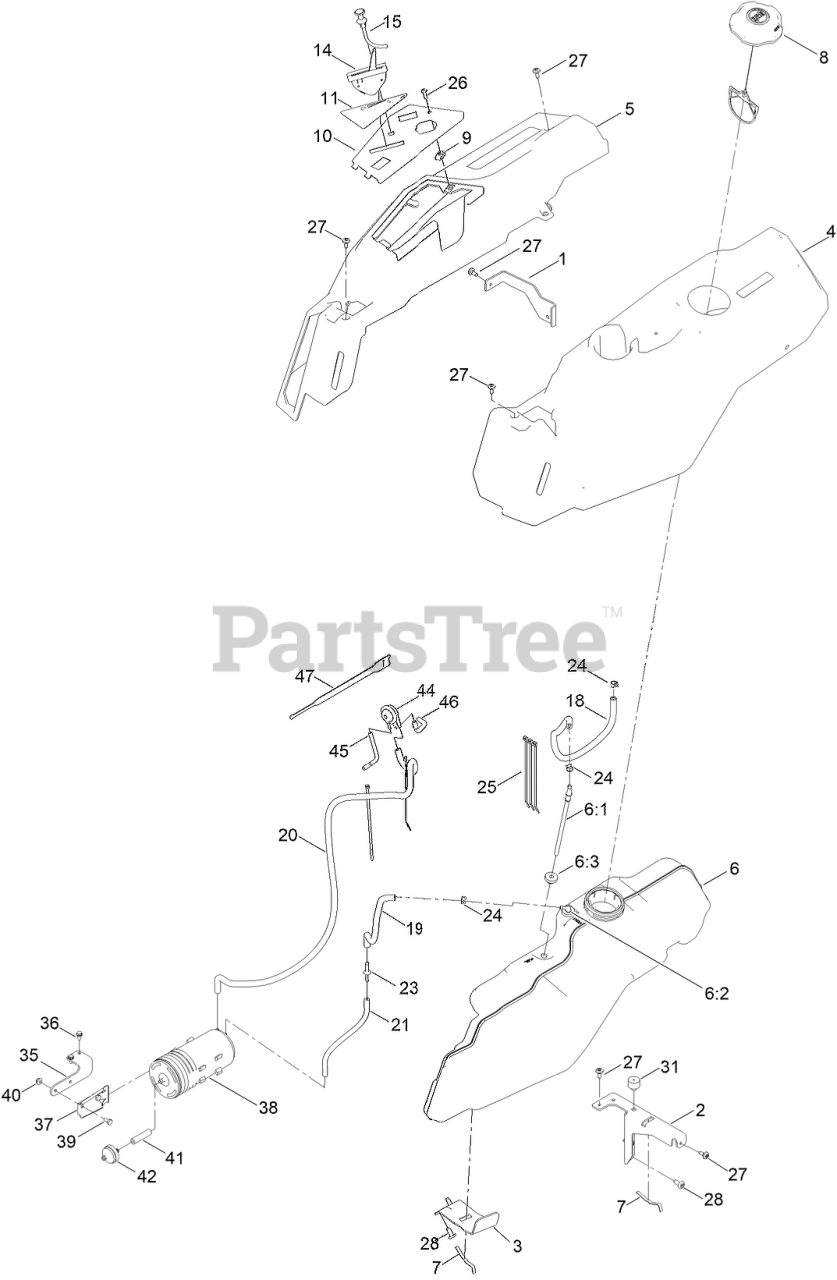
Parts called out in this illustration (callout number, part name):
1	BRACKET-POD
2	SUPPORT-POD, LH
3	SUPPORT-TANK, FUEL
4	POD-LH
5	POD-RH, MYRIDE
6	FUEL TANK ASM
6:1	CONNECTOR-ELBOW, 90 DEG
6:2	FITTING-PLASTIC
6:3	BUSHING
7	SPRING
8	CAP-FUEL, RATCHETING
10	PANEL - CONTROL
11	DECAL-PANEL, CONTROL
14	CABLE-THROTTLE
15	CABLE-CHOKE
18	HOSE-FUEL
19	HOSE-FUEL
20	HOSE-FUEL
21	HOSE-FUEL
23	ADAPTOR-ORIFICE
24	CLAMP-HOSE
25	TIE-CABLE
26	SCREW-PRH
27	SCREW-SHOULDER
31	BUMPER-GROMMET
35	BRACKET-CANISTER, CARBON
36	SCREW-HWH
37	BRACKET-CANISTER, CARBON
38	CANISTER-CARBON, 800CC
39	SCREW-HH
40	NUT-HF
41	HOSE-FUEL
42	FILTER-FUEL, INLINE
44	VALVE-CONTROL, VACUUM
45	HOSE-VENT, FORMED
46	HOSE-VENT, FORMED
47	STRAP-VELCRO, CABLE TIE
